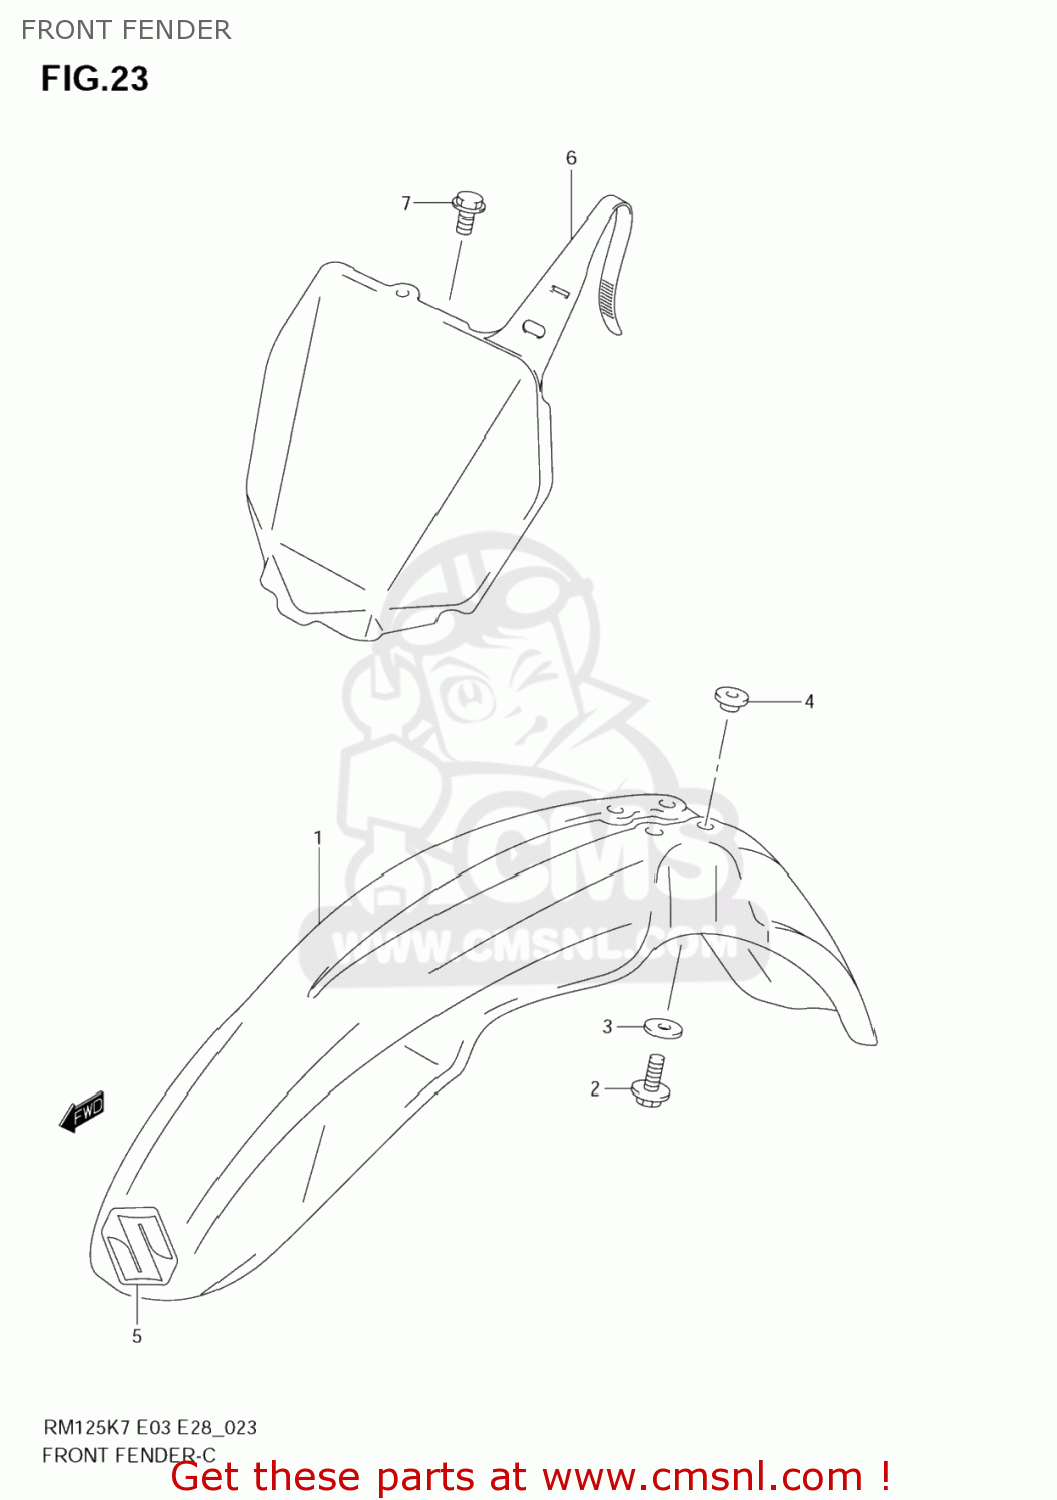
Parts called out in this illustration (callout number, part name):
1	FENDER,FR
2	BOLT
3	WASHER(6.5X28X1.6)
4	WASHER
5	EMBLEM,S
6	PLATE,NUMBER FR
7	BOLT(6X12)
